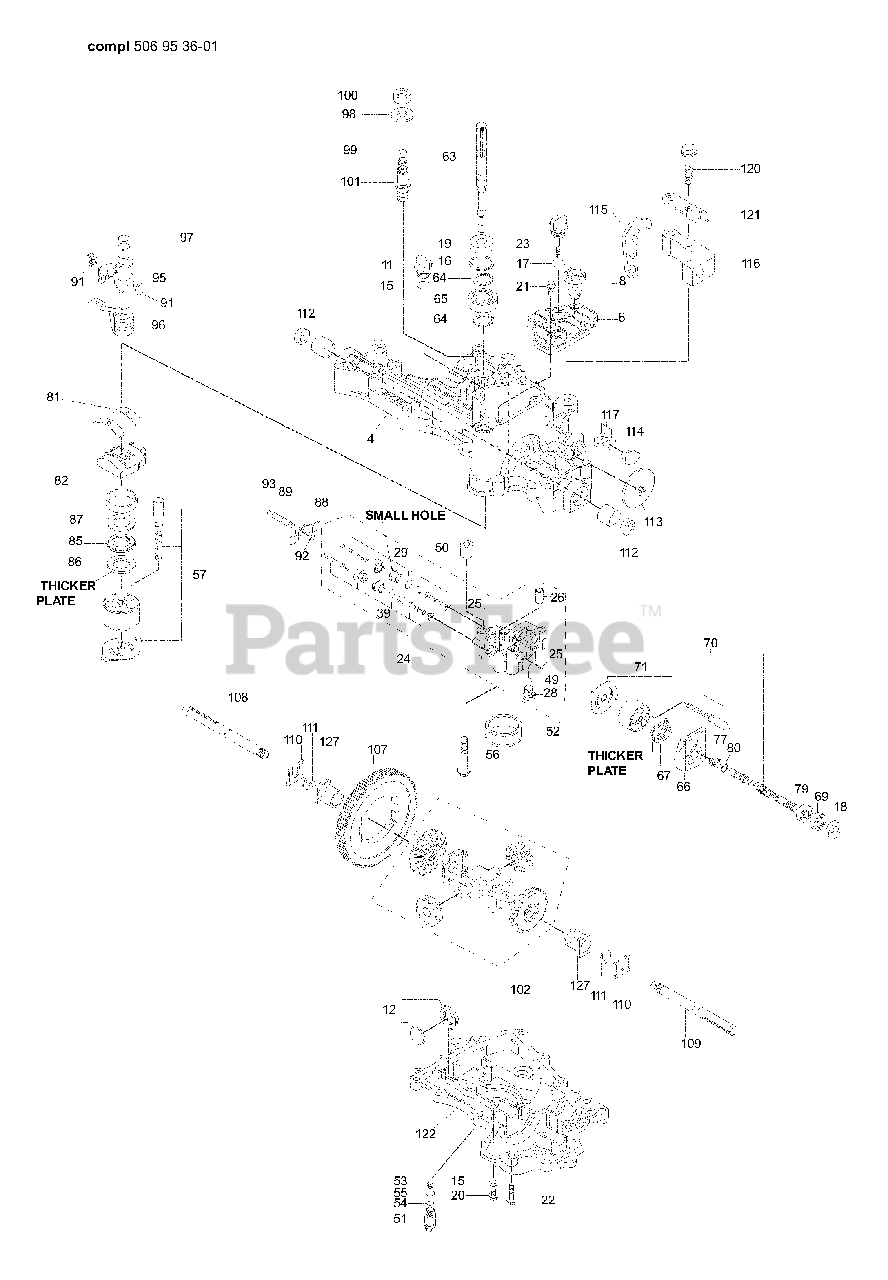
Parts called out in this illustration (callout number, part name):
4	UPPER CASE KIT
8	VENT VALVE 15
11	OIL CAP 20
15	PACKING P18
21	BOLT 8 x 20
22	TAPPING SCREW
24	CENTER CASE KIT
25	KNOCK PIN 3.5
26	KNOCK PIN 12x22
28	PLUG PF 1/2
29	VALVE (A-1 KIT
39	VALVE (A-2 KIT
50	COLLAR 10x20x20
57	CYLINDER BLOCK
63	PUMP SHAFT
64	SNAP RING S15
67	BEARING 51106
69	BALL BEARING
70	MOTOR SHAFT KIT
71	CYLINDER BLOCKKIT
79	BALL BEARING
81	THRUST METAL
82	SWASH PLATE
85	BEARING K81105
86	THRUST PLATE (A
87	THRUST PLATE (B
88	C ARM BYPASS
91	SHIFT BLOCK KIT
92	SNAP RING E5
95	CONTROL SHAFT
96	SP(TORSION 630
101	FULCRUM 10
102	DIFFERENTIAL GEAR KIT
107	FINAL GEAR 97
108	AXLE SHAFT L
109	AXLE SHAFT R
110	THRUST WASHER
112	SEAL 19x32x8
113	BRAKE DISK
114	BRAKE SHOE
115	BRAKE LEVER
116	LEVER STAY
120	BOLT 10x45
122	LOWER CASE
127	BUSHING 19x25
506953601	TRANSMISSION
